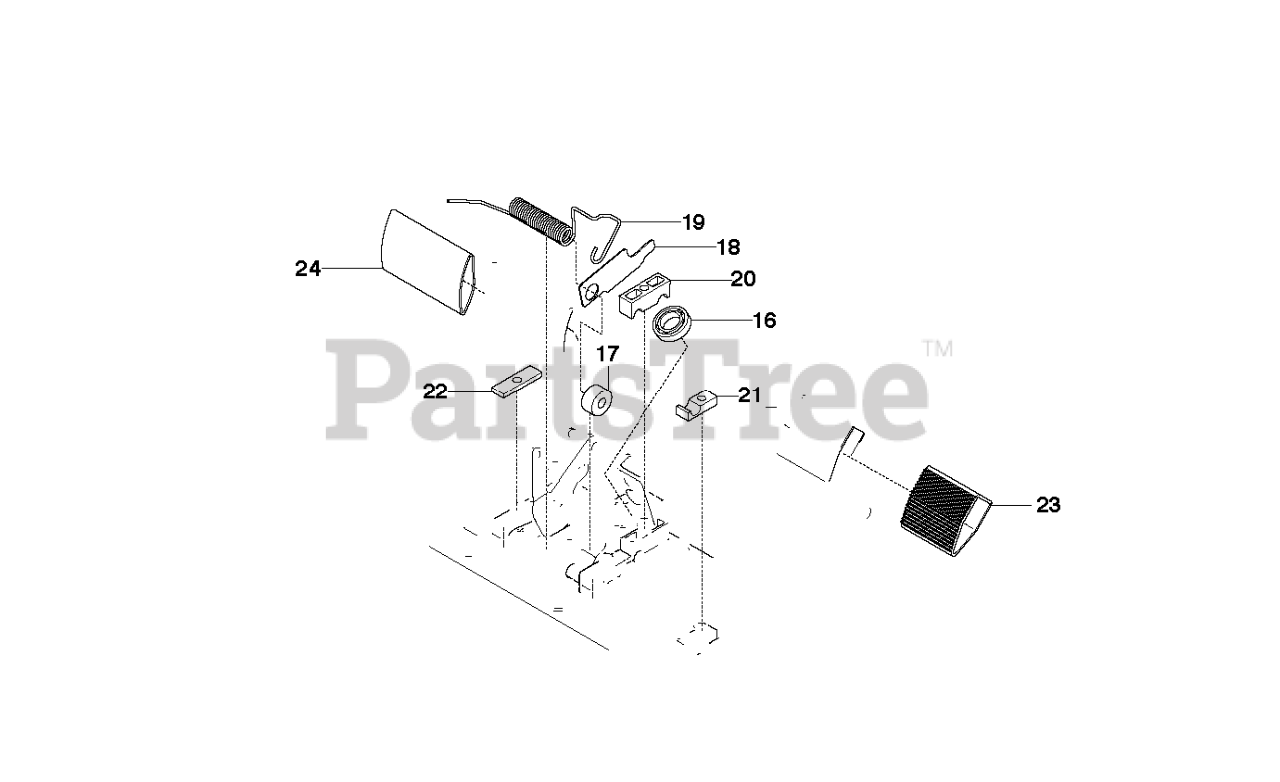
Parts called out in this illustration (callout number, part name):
16	BALL BEARING 6002-2RS1
17	ROLLER
18	PLATE
19	SPRING
20	PEDAL SHAFT CLAMP
21	SUPPORT
22	PLATE
23	PEDAL RUBBER
24	PEDAL RUBBER, SF
